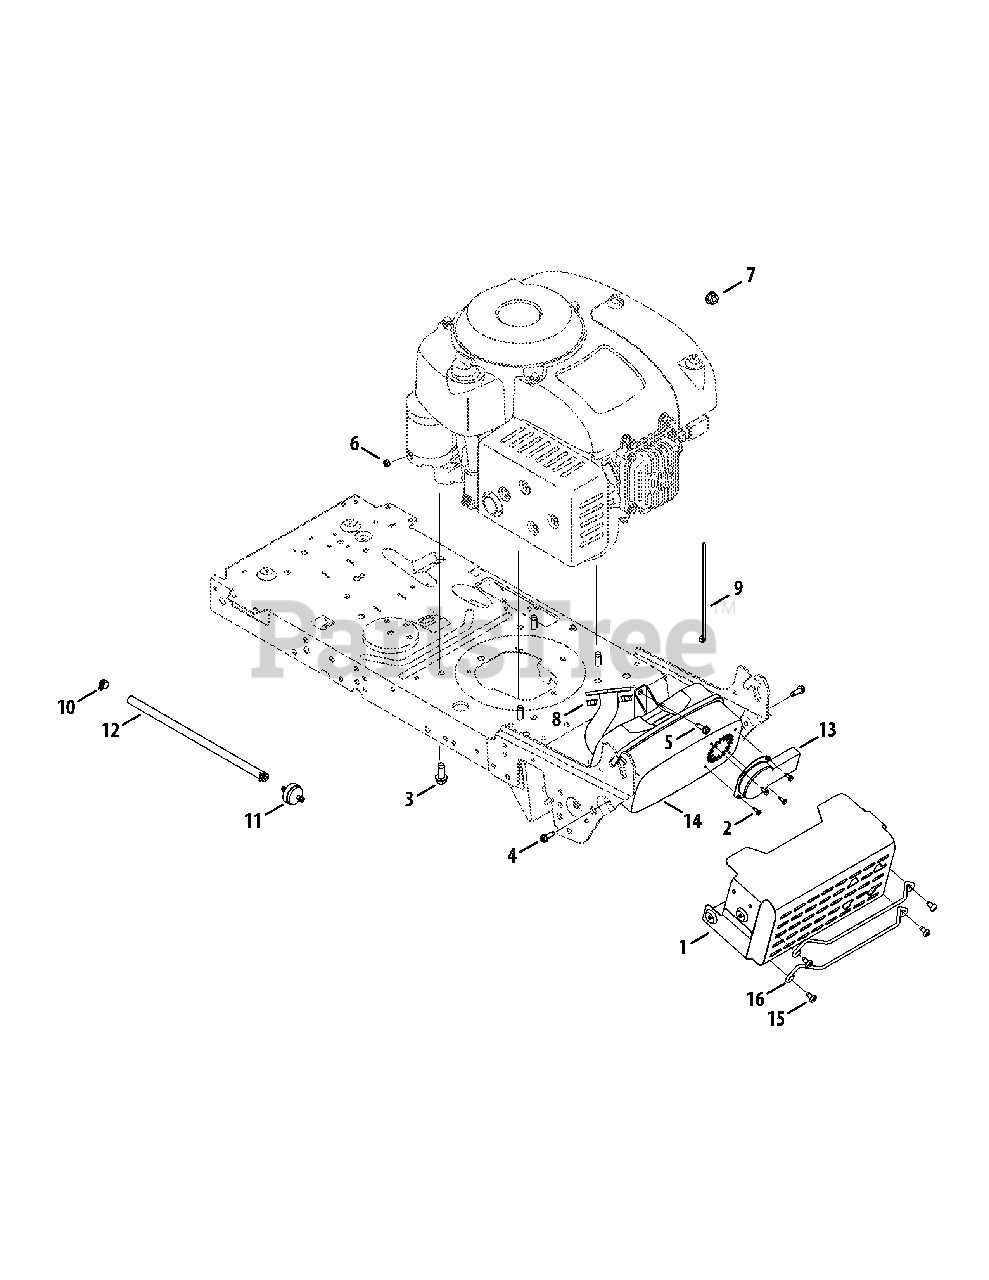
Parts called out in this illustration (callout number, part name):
1	Muffler Shield Assembly
2	Screw, 8-18 x .500
3	Screw, 3/8-16 x 1.0
4	Screw, 1/4-20 x .500
5	Screw, 1/4-20 x .750
6	Nut, M6-1, Hexlock
7	Flange Lock Nut, 3/8-16
8	Flange Nut, M8-1.25
9	Cable Tie
10	Clamp Hose, .490 diameter
11	Fuel Filter
12	Fuel Hose
13	Muffler Deflector Long
14	Muffler, Single Inlet
15	Pan Torx Screw 1/4
16	Muffler Guard Rod
